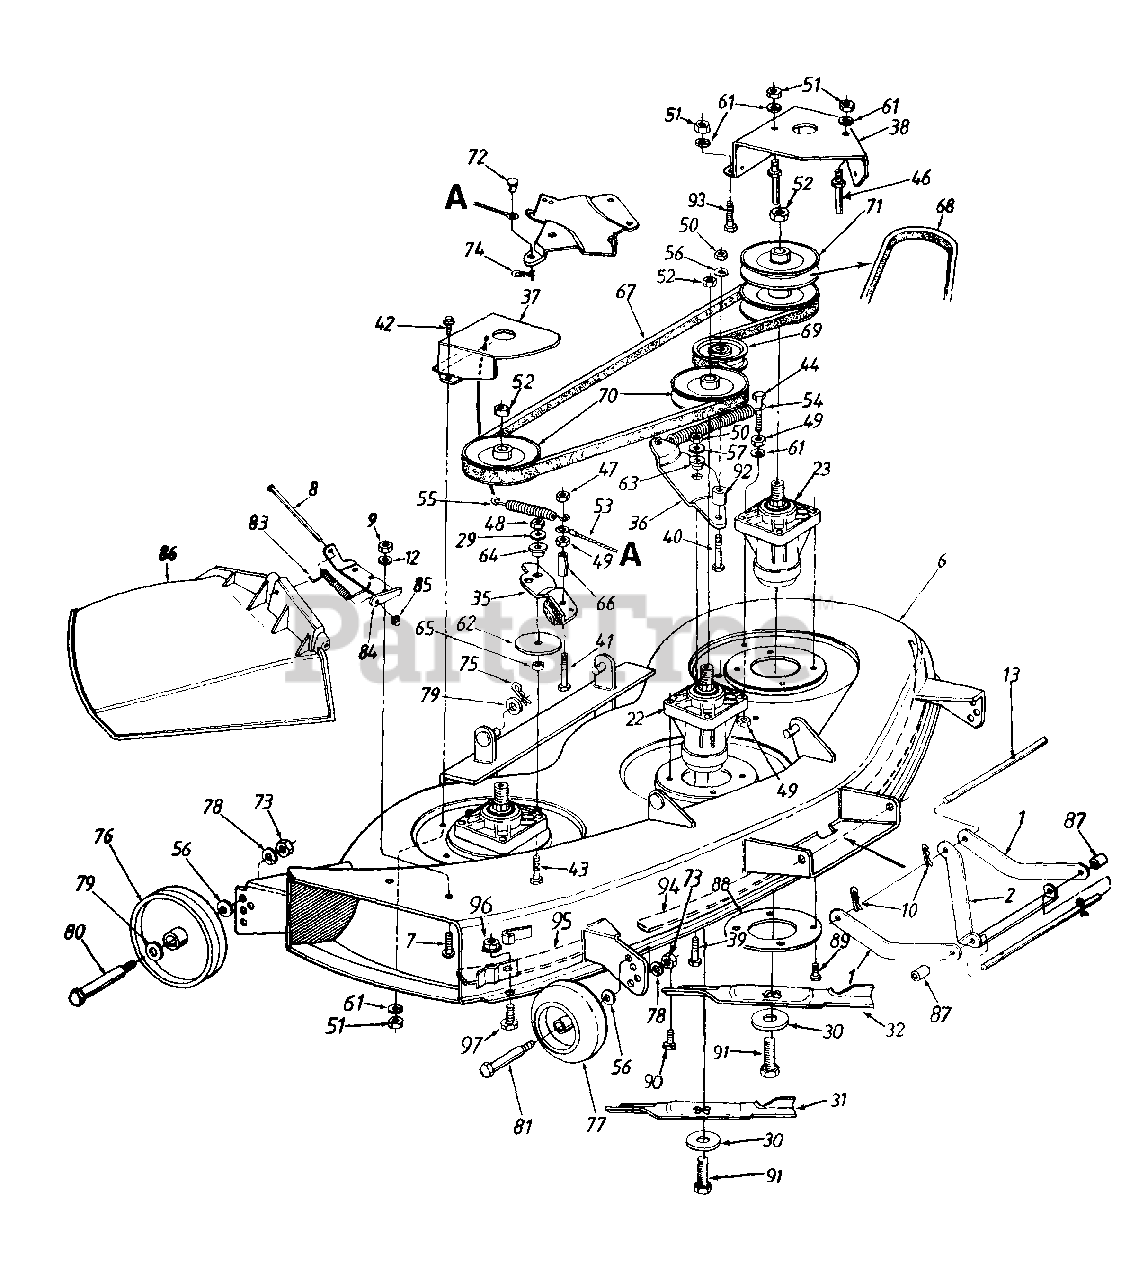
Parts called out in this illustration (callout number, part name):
8	Hinge Pin
9	Hex Nut 1/4-20 Thd.
10	Hairpin Clip
12	Bell-Wash. 1/4" I.D.
13	Deck Connecting Rod
22	Spindle Ass'y. (R.H. & Center)
23	Spindle Ass'y. (L.H.)
29	Lock Wash. 5/16" I.D.
30	Bell-Wash. .47" I.D. x 1.5"
31	High Lift Blade 14.88" Lg. (Middle)
32	High Lift Blade 16.28" Lg. (R.H. & L.H.)
35	Deck Brake Brkt. Ass'y.
39	Hex Bolt 3/8-24 x 1.0" Lg.
40	Hex Bolt 3/8-24 x 2" Lg.
41	Hex Bolt 1/4-28 x 1.75" Lg.
42	Hex Wash. Hd. Tap-Scr. 1/4-20 x .5" Lg.
43	Hex Bolt 5/16-24 x 1.5" Lg. (Grade 5)
44	Hex Bolt 1/4-28 x 1.5" Lg.
46	Belt Guard Pin 1/4" Dia.
47	Hex Cent. L-Nut 1/4-28 Thd.
48	Hex Nut 5/16-24 Thd.
49	Hex Nut 1/4-28 Thd.
50	Hex Nut 3/8-24 Thd.
51	Hex Nut 1/4-20 Thd.
52	Hex Flange L-Nut 5/16-18 Thd.
53	Brake Cable Ass'y.
54	Extension Spring 6.17" Lg.
55	Extension Spring 3.97" Lg.
56	Bell-Wash. .38" I.D. x .88" O.D.
57	Bell-Wash. .39" I.D. x 1.13" O.D.
61	L-Wash. 1/4" I.D.
62	Fl-Wash 5/16" I.D. x 3" O.D.
63	Shld. Spacer.625" I.D.
64	Shld. Spacer
65	Spacer .34" I.D.
66	Spacer .326" I.D.
67	V-Belt
68	V-Belt
69	Fl-Idler Pulley 3.5" O.D.
70	Pulley 5.0" Dia.
71	Double Pulley 5.0" Dia.
72	Clevis Pin 1/4" Dia. x .53" Lg.
73	Hex Nut 3/8-16 Thd.
74	Intern. Cotter Pin 5/16" Dia.
75	Intern. Cotter Pin 3/8 Dia
76	Deck Wheel 5" Dia.
77	Deck Wheel w/Insert 5" Dia.
78	L-Wash 3/8" I.D
79	Fl-Wash. .531" I.D.
80	Shoulder Bolt .498" Dia. x 1.64" Lg
81	Shoulder Bolt
83	Torsion Spring
84	Hinge Mtg Brkt.
85	Push Nut
86	Chute Ass'y. Comp.
87	Spacer 5/8" I.D. x 7/8" O.D.
90	Hex Wash. Hd. Scr. 5/16-18 x .75" Lg.
91	Hex L-Bolt 7/16-20 x 1" Lg.
92	Spacer 38" I.D.
93	Hex Bolt 1/4-20 x .5" Lg.
96	Hex Sems Nut 1/4-20 Thd.
97	Carriage Bolt 1/4-20 x .5" Lg.
